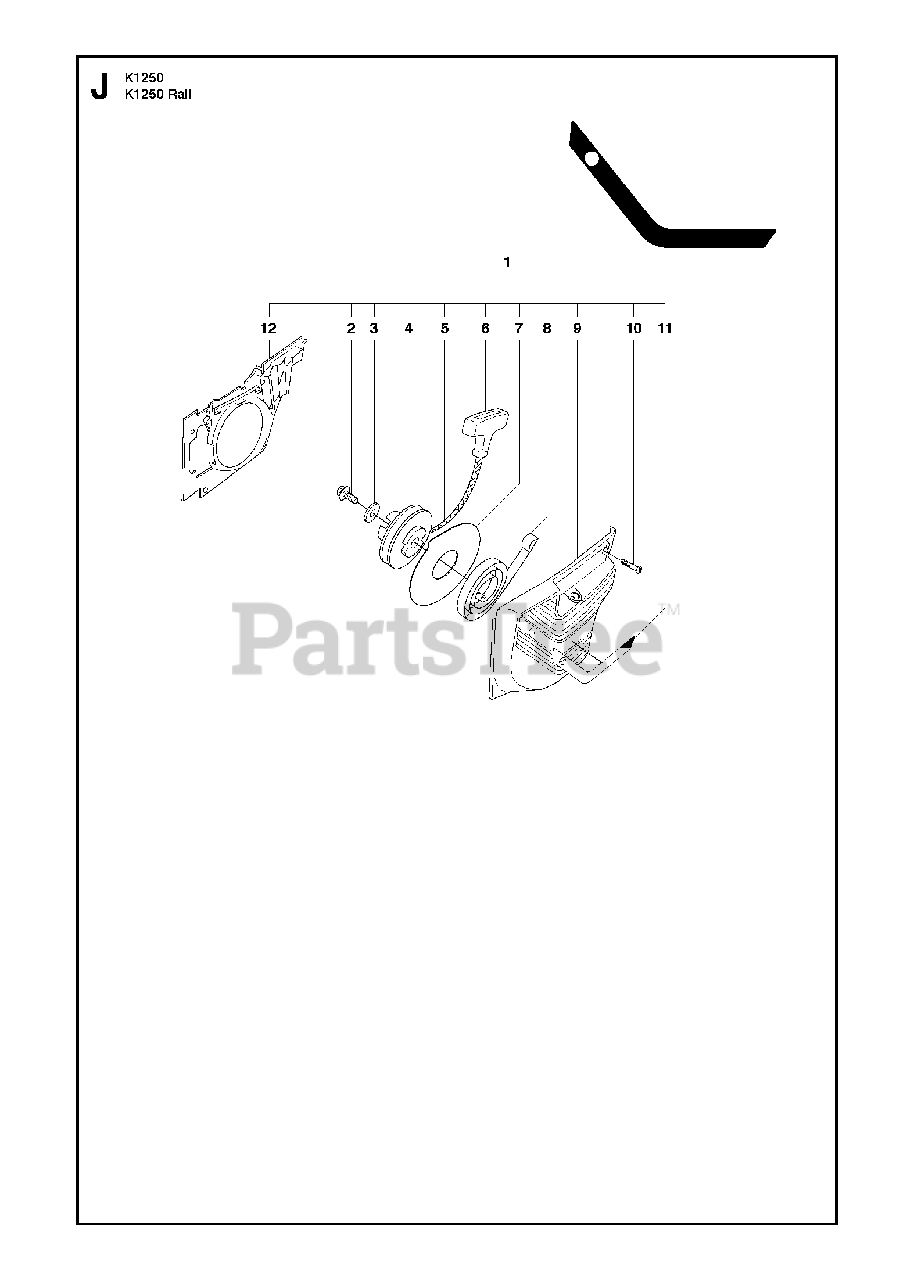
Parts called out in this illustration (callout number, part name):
1	STARTERIncl. 2-12
2	SCREW IHSCT
4	STARTER PULLEY
5	STARTER CORD
6	STARTER HANDLE
7	DAMPING DISC
8	RECOIL SPRING
9	STARTER COVER
10	SCREW CCRPANMO
12	AIR CONDUCTORK1250 A
12	AIR CONDUCTORK1250 Rail Stop Switch
